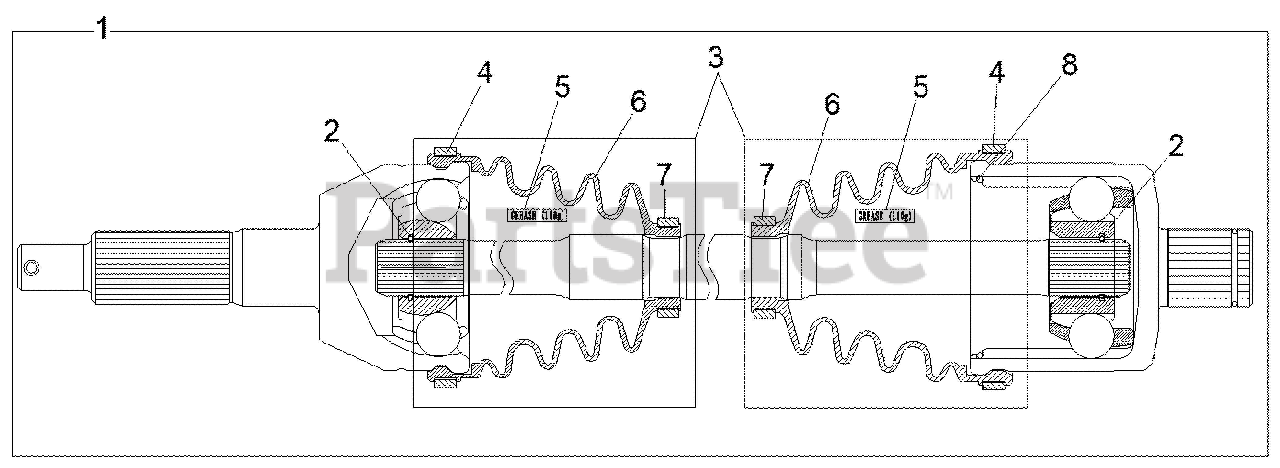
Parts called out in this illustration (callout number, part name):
1	ASM-DRIVESHAFT,REAR
2	CIRCLIP(PR-3041)
3	KIT-BOOT(PR-8071)
4	CLAMP-LARGE(PR-0027)
5	GREASE(K575/VW738)
6	BOOT(PR-0025)
7	CLAMP-SMALL(PR-0026)
8	RING-RUBBER(JIB)
